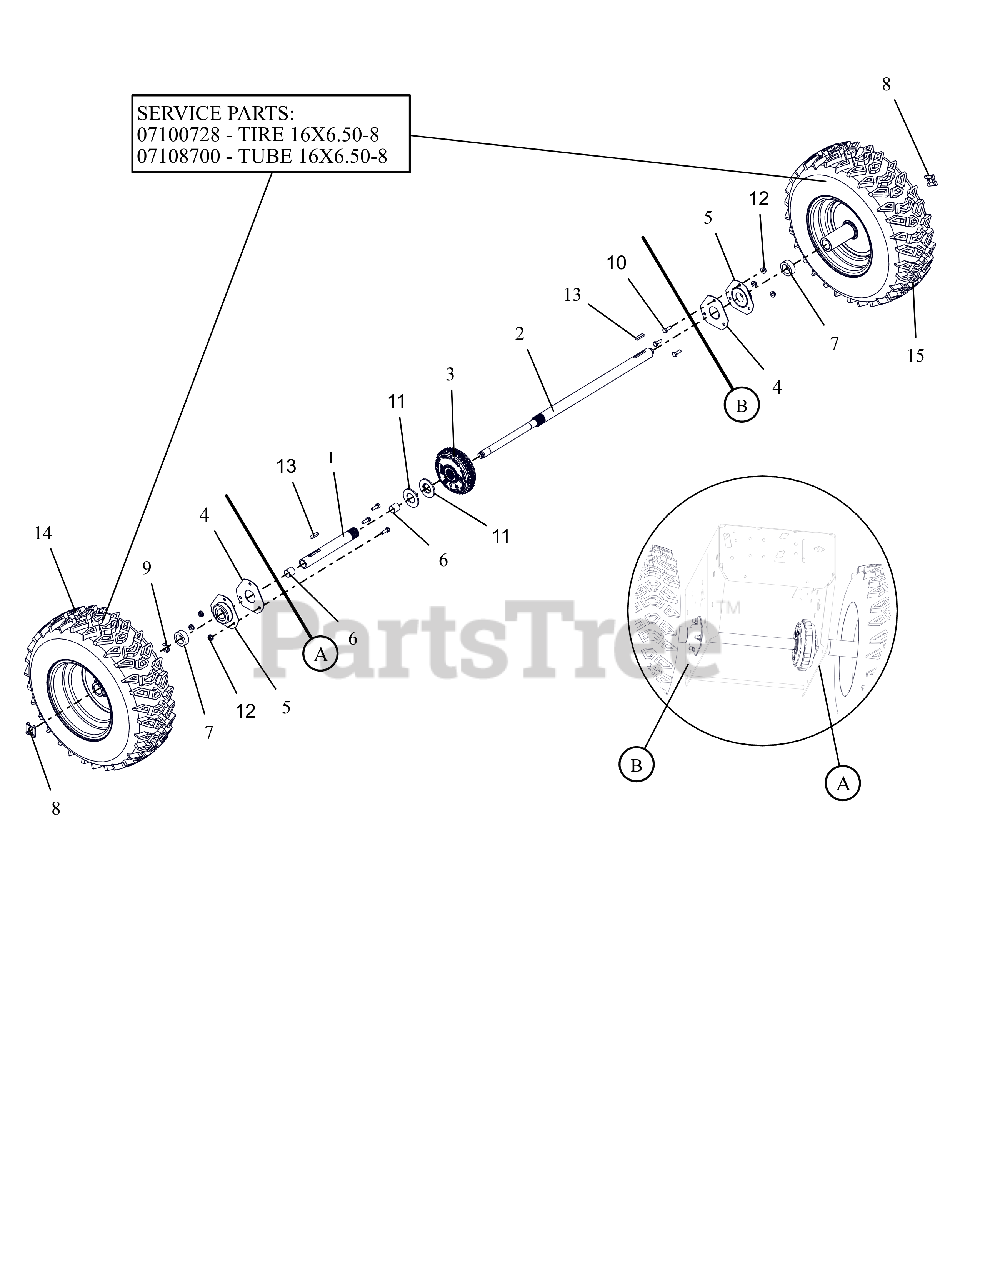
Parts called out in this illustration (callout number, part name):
1	AXLE, SHORT-AUTO W/BUSHINGS
2	AXLE, LONG-PRO AUTO DIFF
3	DIFFERENTIAL, AUTOMATIC
4	PLATE, BEARING SPACER
5	BRG-FLG 1.003/1.000 3 BOLT
6	BSHG-SLV .706X.764X.75 BRZ
7	SPACER, PRO AXLE BEARING
8	CLIP, SNAP .625 DIA
9	RG-RTNG-EXT .625X.042
10	BLT, HEX .25-20X.75 G5 ZCC
11	WSHR, FLT 1.062X2.000X.134 ZCC
12	NUT-LK-CTR-FLG .25-20 ZC120
13	KEY-RECT .25X.188X1.00
14	TIRE/WHEEL,RH 16X6.5-8 DIFF T2
15	TIRE/WHEEL,LH 16X6.5-8 DIFF T2
15	TIRE, 16X6.50-8 K478
15	TUBE
